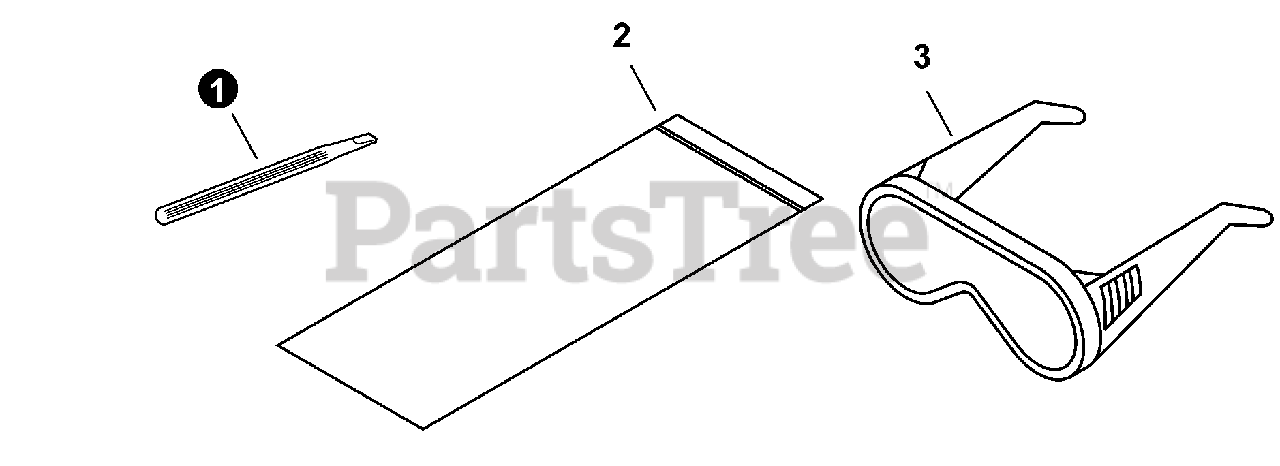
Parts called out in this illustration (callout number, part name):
1	SCREWDRIVER, PLASTIC
2	BAG, TOOL
3	GLASSES, SAFETY
